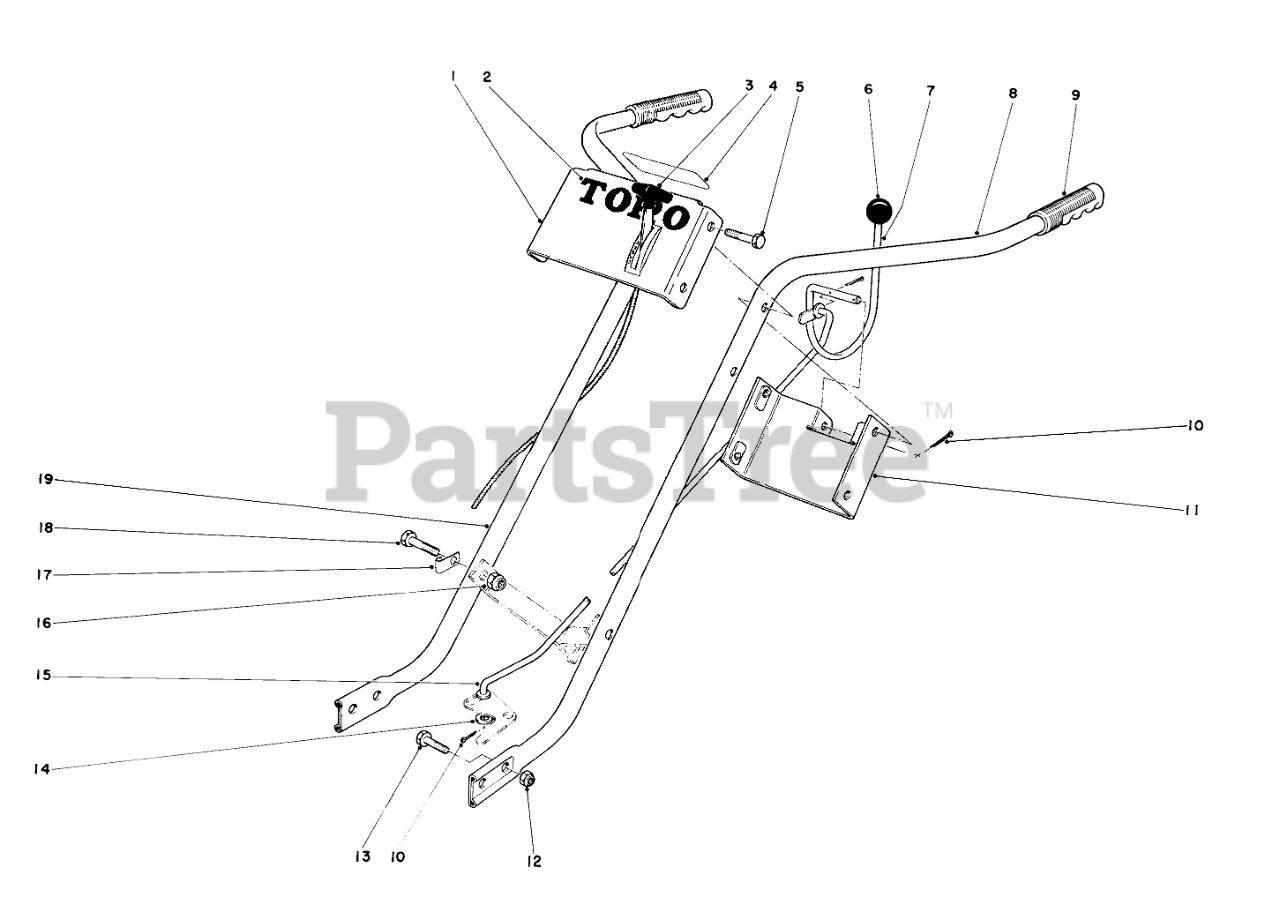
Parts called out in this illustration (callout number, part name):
1	Control Plate
2	Decal, Toro
3	Throttle
4	Decal Clutch
5	SCREW-HH
6	KNOB-CONTROL
7	Clutch Control
8	Handle L.H.
9	Handle Grip
10	PIN-COTTER
11	Handle Brace
12	SCREW-HH
13	SCREW-HH
14	WASHER-FLAT
15	Clutch Rod
16	NUT-LOCK, CONE
18	SCREW-HH
19	Handle R.H.
